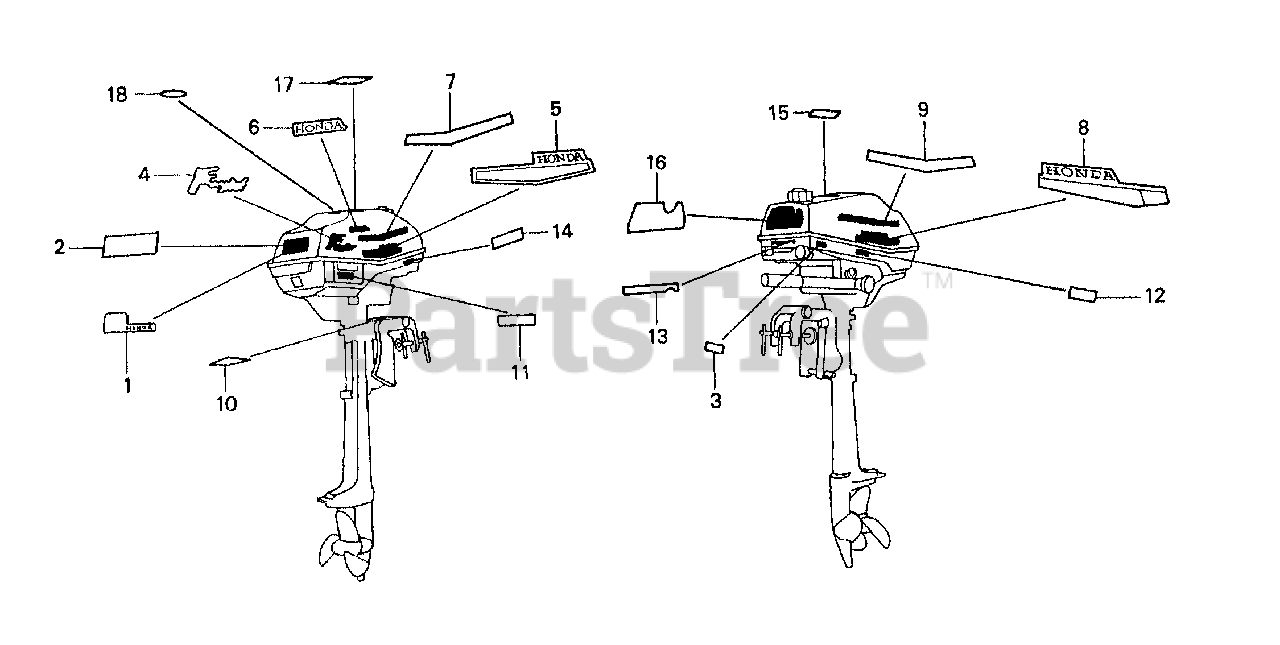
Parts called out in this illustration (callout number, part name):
3	MARK, SPARE CLIP (E)
11	MARK, FUEL VALVE (E)
12	LABEL, OIL CAUTION (E)
13	MARK, INDICATION (E)
14	CAUTION, STORING
15	LABEL, RECOIL CAUTION (E,F)
